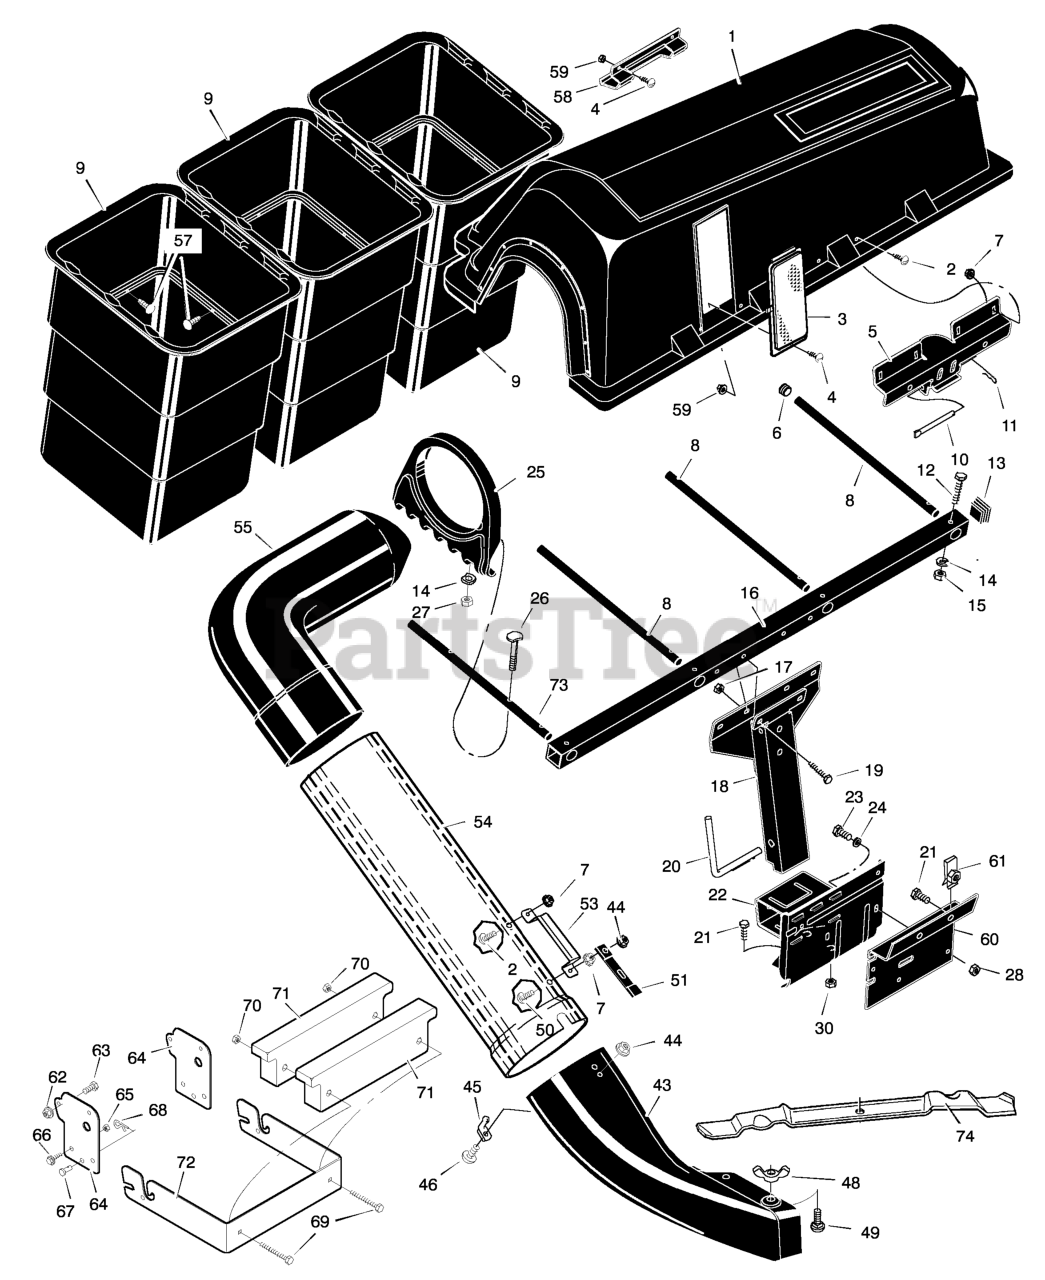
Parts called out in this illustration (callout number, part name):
1	Cover, Bagger
5	Hinge, Bracket
7	Nut, Hex
8	Tube, Container
9	Container
10	Pin, Cover Hinge
11	Pin, Hair
13	Plug
14	Lockwasher
16	Tube, Support
17	Nut
18	Assembly, Channel
20	Pin, Channel Mount
21	Bolt, Hex
22	Assembly, Bagger Mount
23	Bolt, Hex
25	Holder, Elbow
27	Washer
28	Nut, Super Flange
30	Nut, Hex
43	Tube, Extension
44	Locknut, Flange
45	Pin, Latch
46	Bolt, Carriage
48	Wingnut
49	Bolt, Carriage
51	Latch, Rubber
53	HANDLE, Connect Tube
54	Tube, Connecting
57	Fastener, Panel
58	Handle, Plastic
59	Nut, Hex
60	Bracket, Adapter
62	Nut, Flange
63	Bolt
64	Bracket, Hanger
65	Nut
67	Clevis
68	Hairpin
70	Nut
71	Weight
72	Bracket, Front Weight
73	Tube, Right Container
74	Blade, High Lift
